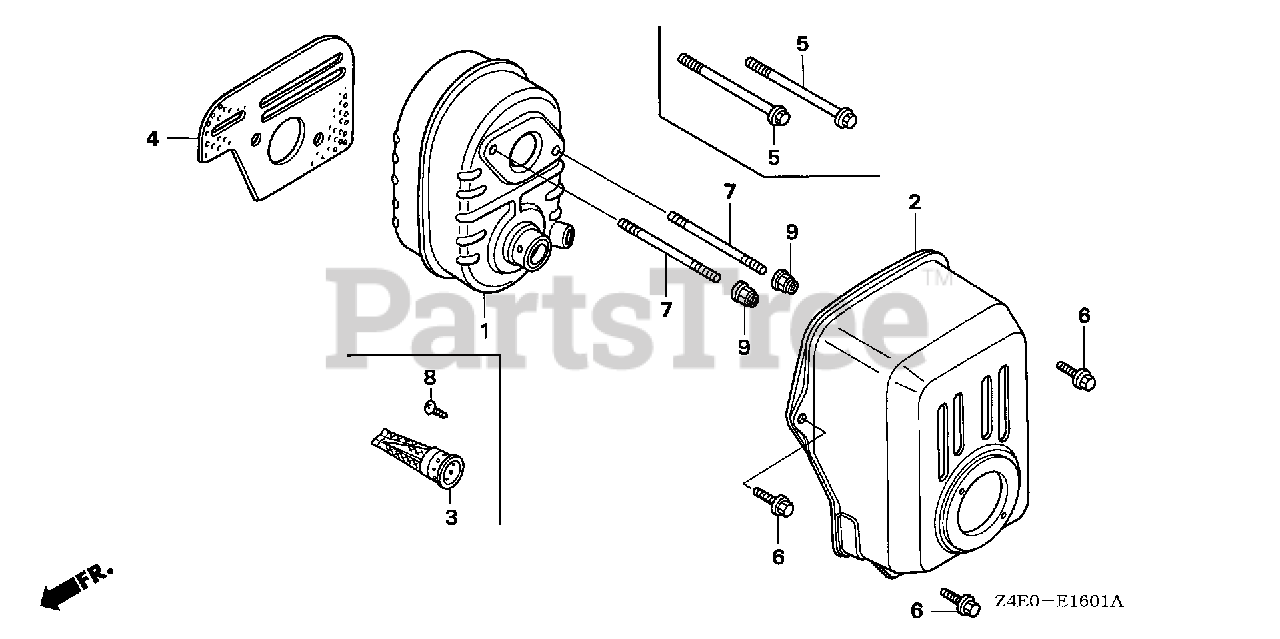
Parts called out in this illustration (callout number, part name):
2	PROTECTOR, MUFFLER
3	ARRESTER, SPARK
4	GASKET, MUFFLER
6	BOLT, FLANGE (6X14) (CT200)
7	BOLT, STUD (6X78) (CT200)
8	SCREW, TAPPING (4X6)
9	NUT, SELF-LOCK (6MM)
